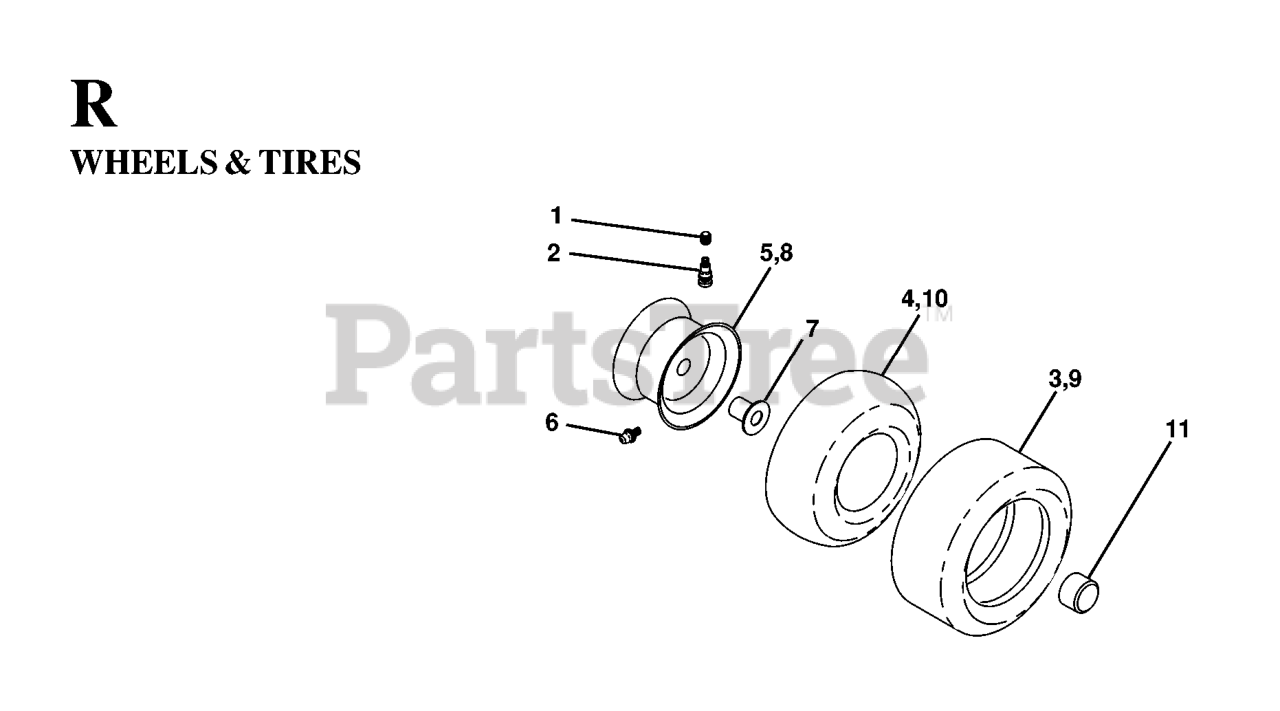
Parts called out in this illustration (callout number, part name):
2	VALVE STEM LT
3	TIRE HEAVY DUTY
4	TUBE.5.3/4.5/6
5	RIM ASM 6" FRONT SILVER
6	FITTING LT
7	BEARING T
8	RIM ASM 8" REAR SILVER
9	TIRE.TS.20X10-8
10	TUBE - UNIVERSAL FOR 8" RIM
11	CAP.HUB.FRONT.LT.BLACK
